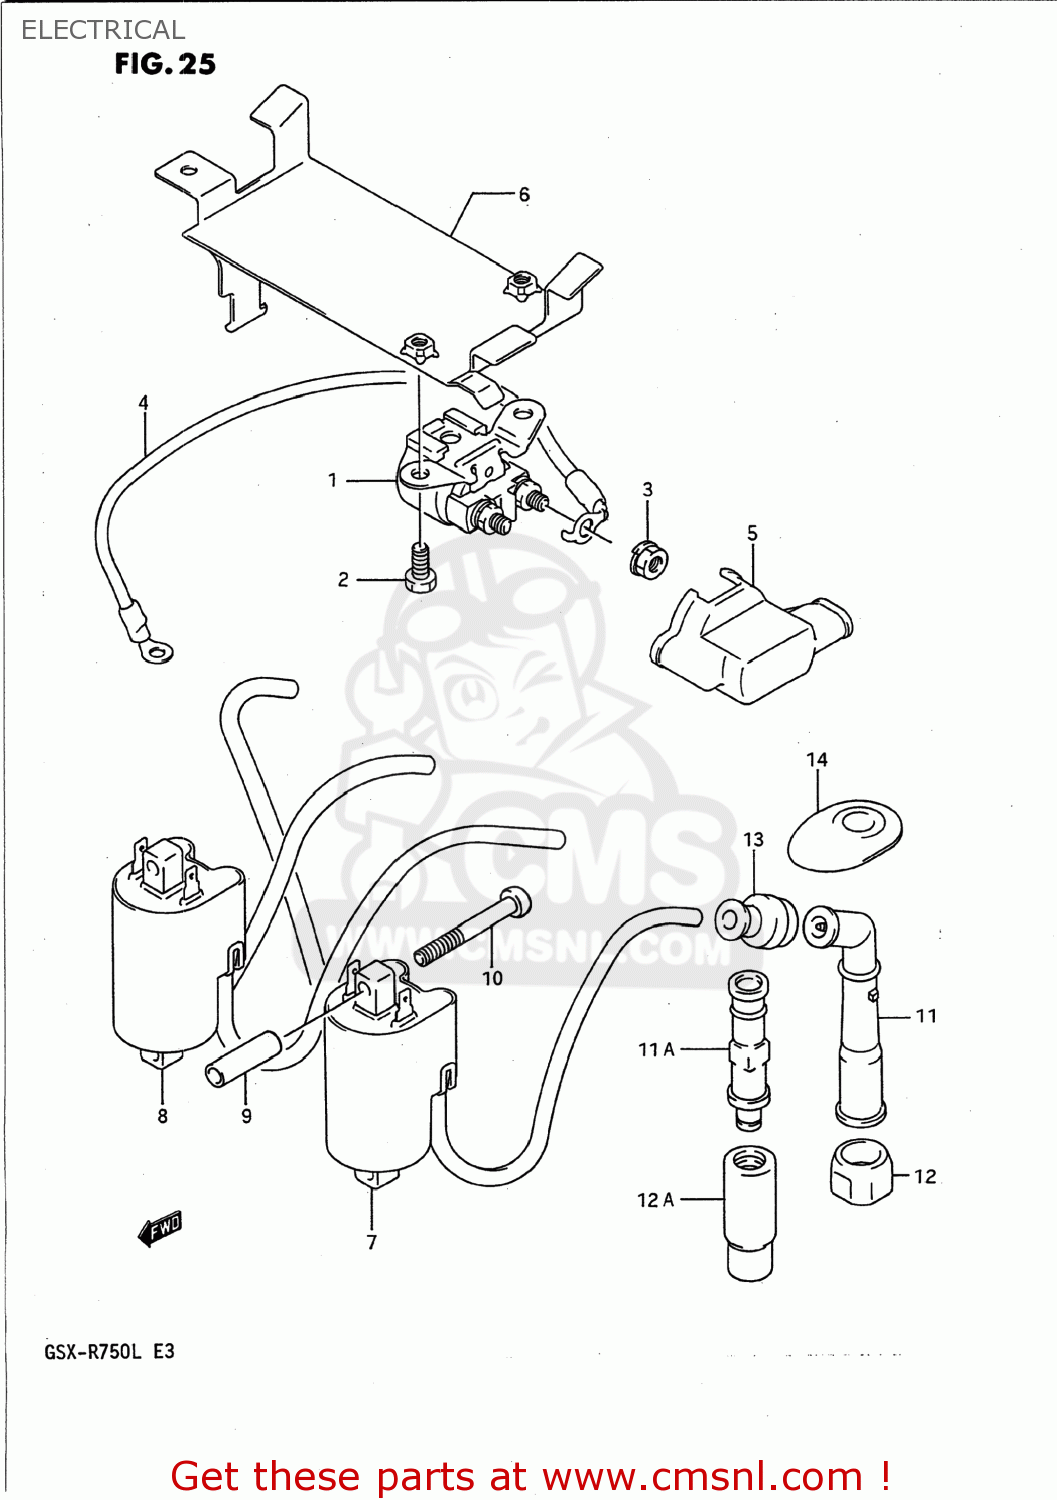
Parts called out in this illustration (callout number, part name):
1	RELAY ASSY,STARTING MOTOR
2	SCREW(6X8)
3	NUT
4	WIRE,STARTER MOTOR LEAD
5	COVER,RELAY ASSEMBLY
6	HOLDER COMP,ELECTRONIC PARTS
7	COIL ASSEMBLY,IGNITION (1-4)
8	COIL ASSEMBLY,IGNITION
9	SPACER(6.4X10X32)
10	SCREW
11	CAP,SPARK PLUG
11A	CAP,SPARK PLUG
12	SEAL,SPARK PLUG
12A	SEAL,SPARK PLUG
13	SEAL,HIGH TENSION CORD
14	COVER,SPARK PLUG CAP
